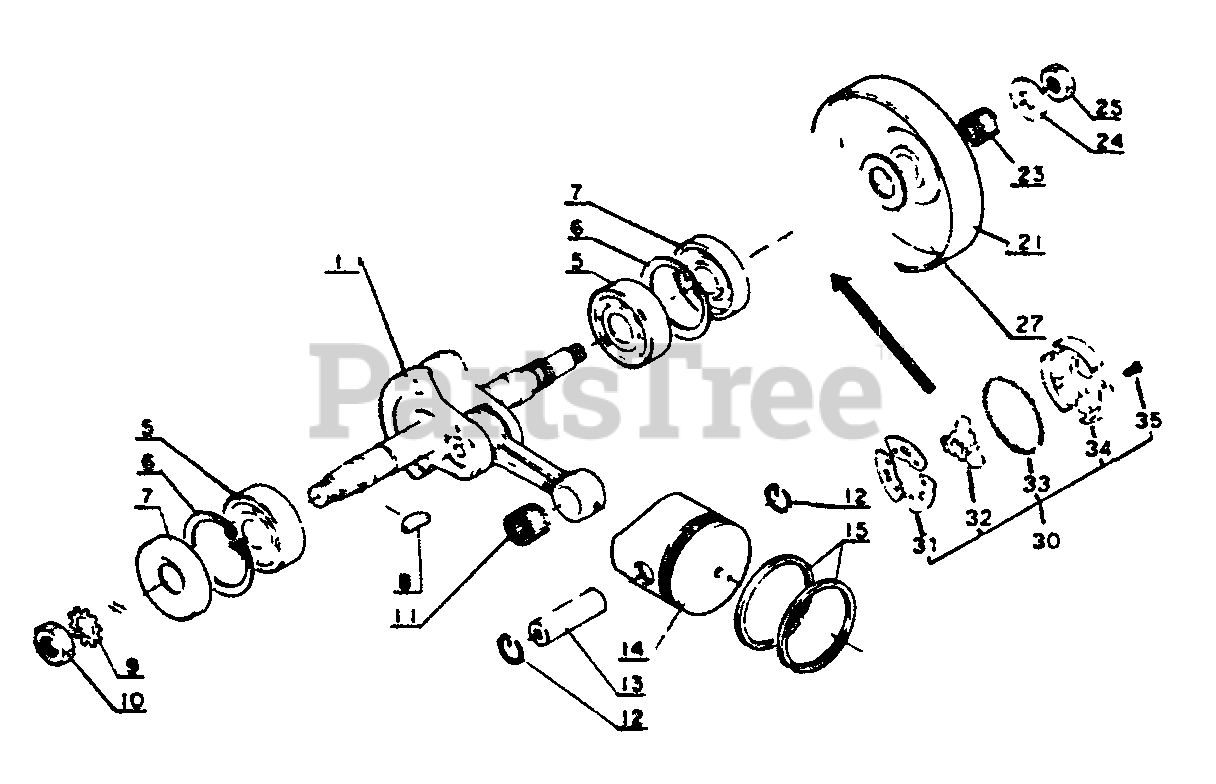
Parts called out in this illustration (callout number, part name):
1	CRANKSHAFT
5	BEARING, BALL - 6201 C3
6	RING, SNAP Ø32
7	SEAL, OIL
11	BEARING, NEEDLE
12	RING, RETAINING
13	PIN, PISTON
15	RING, PISTON
21	CASE, CLUTCH
23	BEARING, NEEDLE 8
24	WASHER, CLUTCH
25	LOCKNUT - 6
27	WASHER, CLUTCH
30	CLUTCH ASSY
31	PLATE, CLUTCH
32	BOSS, CLUTCH
33	SPRING, CLUTCH
34	SHOE SET, CLUTCH (3PCS)
35	SCREW - 4×8
